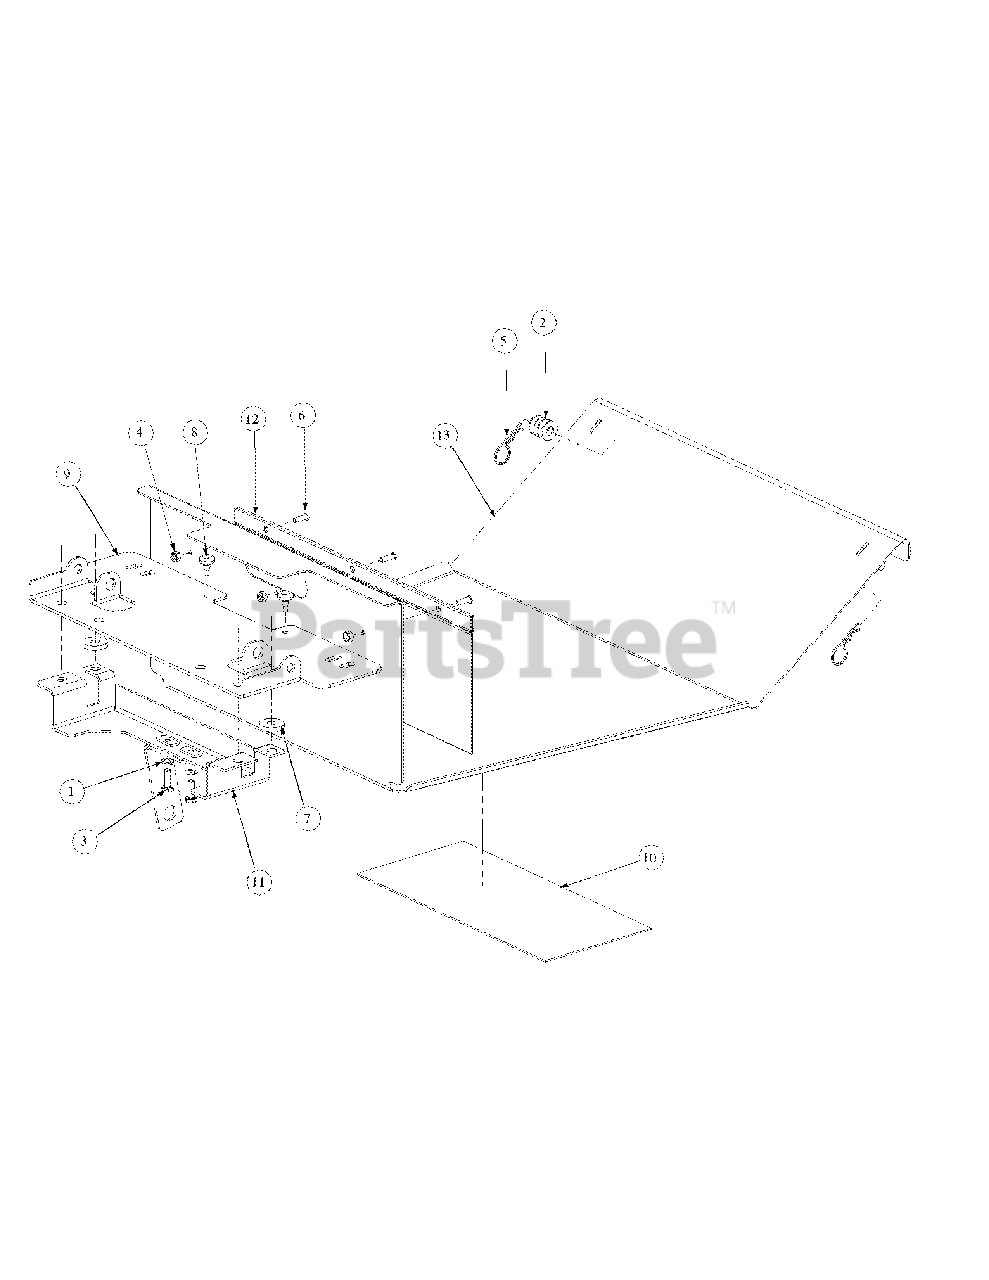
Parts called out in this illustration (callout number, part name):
1	Lock Washer, 1/4
3	Hex Cap Screw, 1/4-20, .75
4	Lock Nut, Nylon Insert, 10-32
5	Hair Pin, 3/8-1/2
6	Screw, Phillips Head, Machine, 10-32 x 5/8
7	Washer
8	Rubber Bumper, .62 OD x .22 Thick
10	Label, Belt Routing and Lubrication
11	Support, Seat Bracket
12	Bag, Debris Storage
13	Floor Panel Assembly
